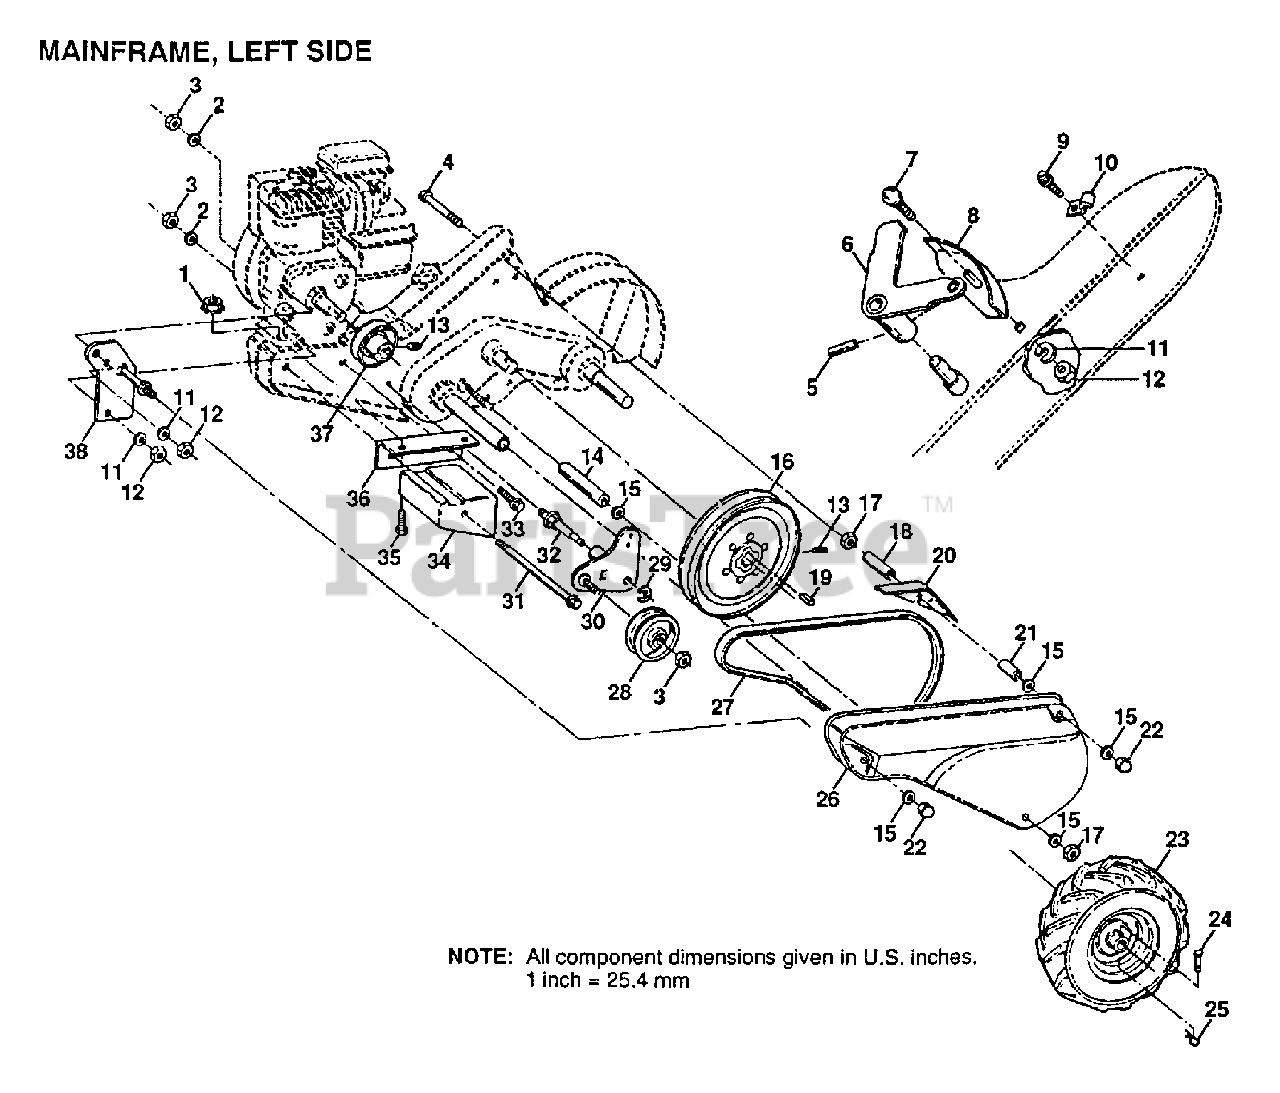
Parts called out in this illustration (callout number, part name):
2	LOCKWASHER
3	NUT.HEX.3/8-16UNC
4	BOLT TI
6	LEVER ASM CRT
7	BOLT
8	PANEL TI
10	CONDIUT CLIP T
11	LOCKWASHER
13	SET SCREW
14	SPACER
15	WASHER
16	"SHEAVE 10"" CRT"
17	NUT.HEX.5/16-18
18	SPACER CRT
19	KEY T
20	GUARD CRT
21	SPLIT SPACER
22	NUT TI
23	TIRE.CHV.13X5.0-6
24	RIVET.DRILL.1.75
25	RETAINER M
27	BELT-V
28	PULLEY-IDLER TI
29	KLIP RING
31	BOLT CRT
32	SHIFT ARM CRT
33	BOLT
34	COUNTERWEIGHT CRT
35	BOLT.HEX.5/16-1.5
36	BRACKET LH CRT
37	ENGINE SHEAVE
38	BELT GUARD BRKT
